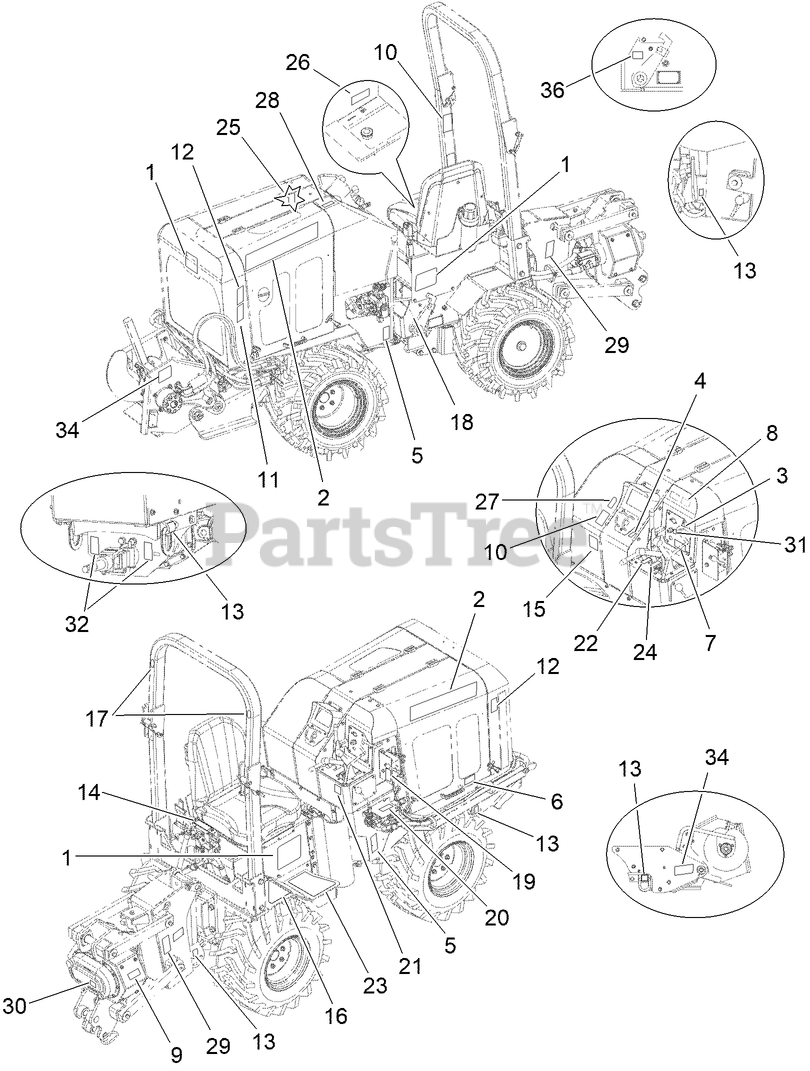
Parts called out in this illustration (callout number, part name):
1	DECAL
2	MAXI SNEAKER 370 MODEL ID
3	IGNITION
4	HAND THROTTLE OPERATION
5	WARNING CRUSHING FORCE
6	WARNING NO ETHER/STARTER FLUID ISO
7	WARNING READ MANUAL ISO
8	WARNING ONE CALL NOTIFICATION ISO
9	AMPLITUDE CHART
10	WARNING ROLLOVER - FOLDABLE ROPS
11	CAUTION HOT PARTS
12	WARNING MOVING PARTS ISO
13	TIE DOWN LOCATION
14	PLOW CONTROL
15	SERVICE LUBE CHART
16	NON-SKID
17	RED HI VIS 1.5" REFLECTORS
18	HYDRA BORE CONTROL
19	PLOW/TRENCHER LIFT SELECT
20	DIGGING CHAIN FORWARD/REVERSE
21	GROUND DRIVE CONTROL
22	PARKING BRAKE
23	NON-SKID
24	DIGGING CHAIN/PLOW RAISE/LOWER
25	FUSE RELAY BLOCK
26	DIESEL FUEL ISO
27	CAUTION WEAR HEARING PROTECTION
28	HYDRAULIC RESIVOIR (THF) ISO
29	WARNING MOVING PARTS
30	OIL LEVEL DECAL
32	DANGER ROTATING SHAFT
34	DANGER CHAIN AND AUGER ISO
36	DECAL-STEERING FRAME LOCK
